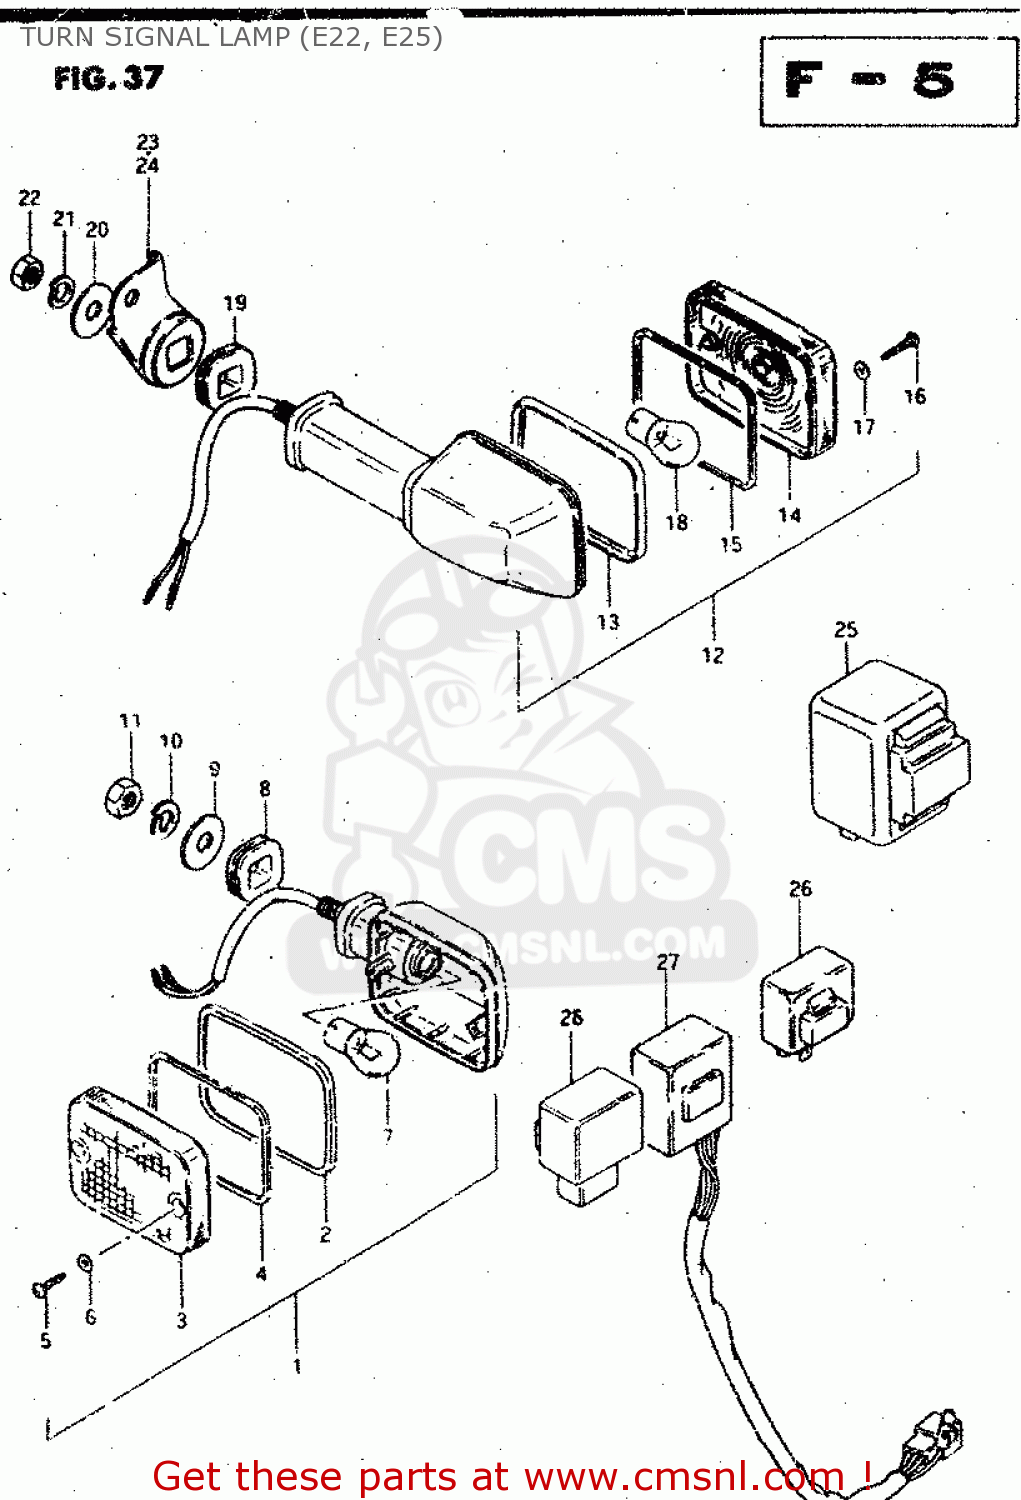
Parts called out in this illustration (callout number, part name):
1	LAMP ASSY,FR T
2	RIM
3	LENS
4	GASKET (NAS)
5	SCREW
6	GASKET (NAS)
7	BULB(12V21W)
8	CUSHION
9	WASHER (10.5X30X2.3)
10	LOCK WASHER
11	NUT
12	LAMP ASSY,RR T
13	RIM
14	LENS
15	GASKET (NAS)
16	SCREW
17	GASKET (NAS)
18	BULB(12V21W)
19	CUSHION
20	WASHER (10.5X30X2.3)
21	LOCK WASHER
22	NUT
23	BRACKET,RR TURNSIGNAL LAMP,R
24	BRACKET,RR TURNSIGNAL LAMP,L
25	RELAY, TURN SIGNAL
26	RELAY ASSY,TURNSIGNAL
27	UNIT,TURN SIGNAL CONTROL
28	UNIT,TURN SIGNAL CONTROL
